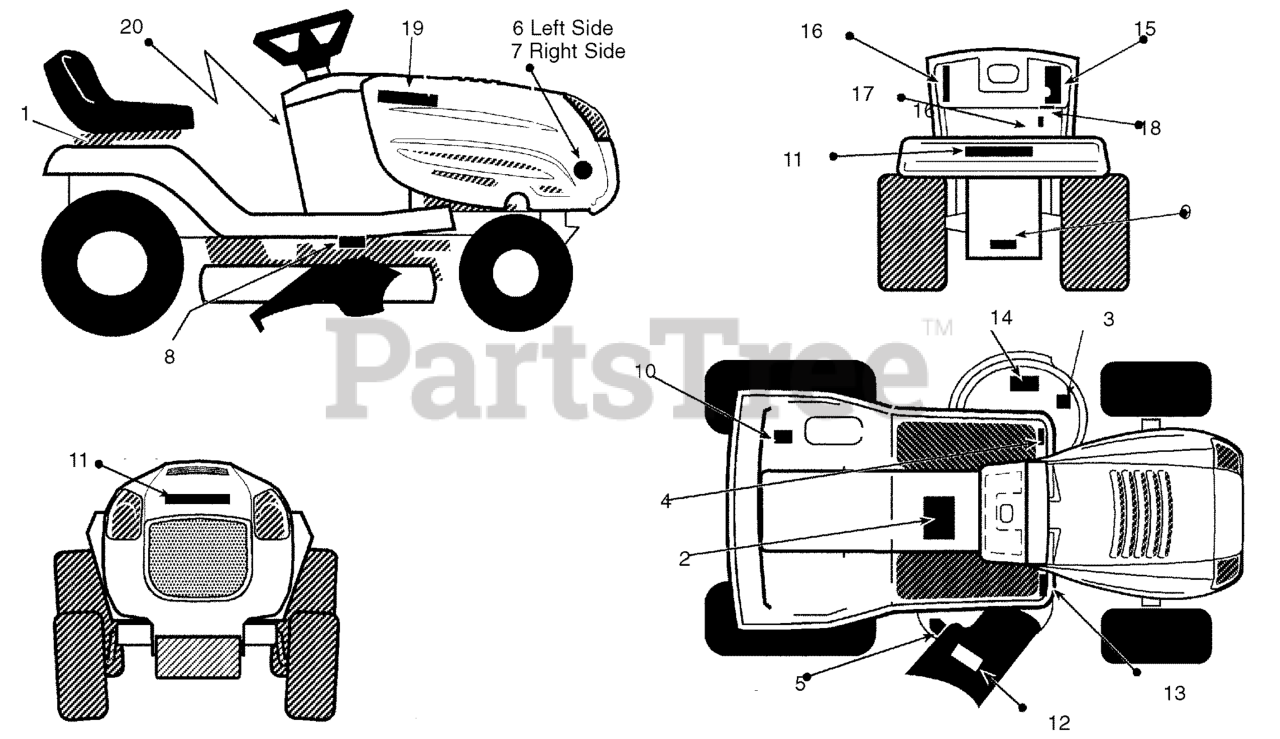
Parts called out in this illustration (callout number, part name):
1	DEKA (Battery)
2	Warning (Console - Center)
3	NO STEP (Mower Deck - Left Side)
4	Park / Brake
5	Cut Finger (Mower Deck -Right Side)
6	20/42 Auto Twin - Left Side
7	20/42 Auto Twin - Right Side
8	Gage Wheel Level
9	Warning Load Limit (Rear)
10	Auto Disconnect
11	Craftsman Logo
12	Mulch Kit Installed
13	Hydro Drive
15	Diagnostic Dash
16	20 HP B&S V-Twin
17	Ignition / Parking Brake
18	Throttle
19	Deck Height Adjust
20	Deck Height Control
21	Craftsman Nameplate
22	Fuel Gauge
